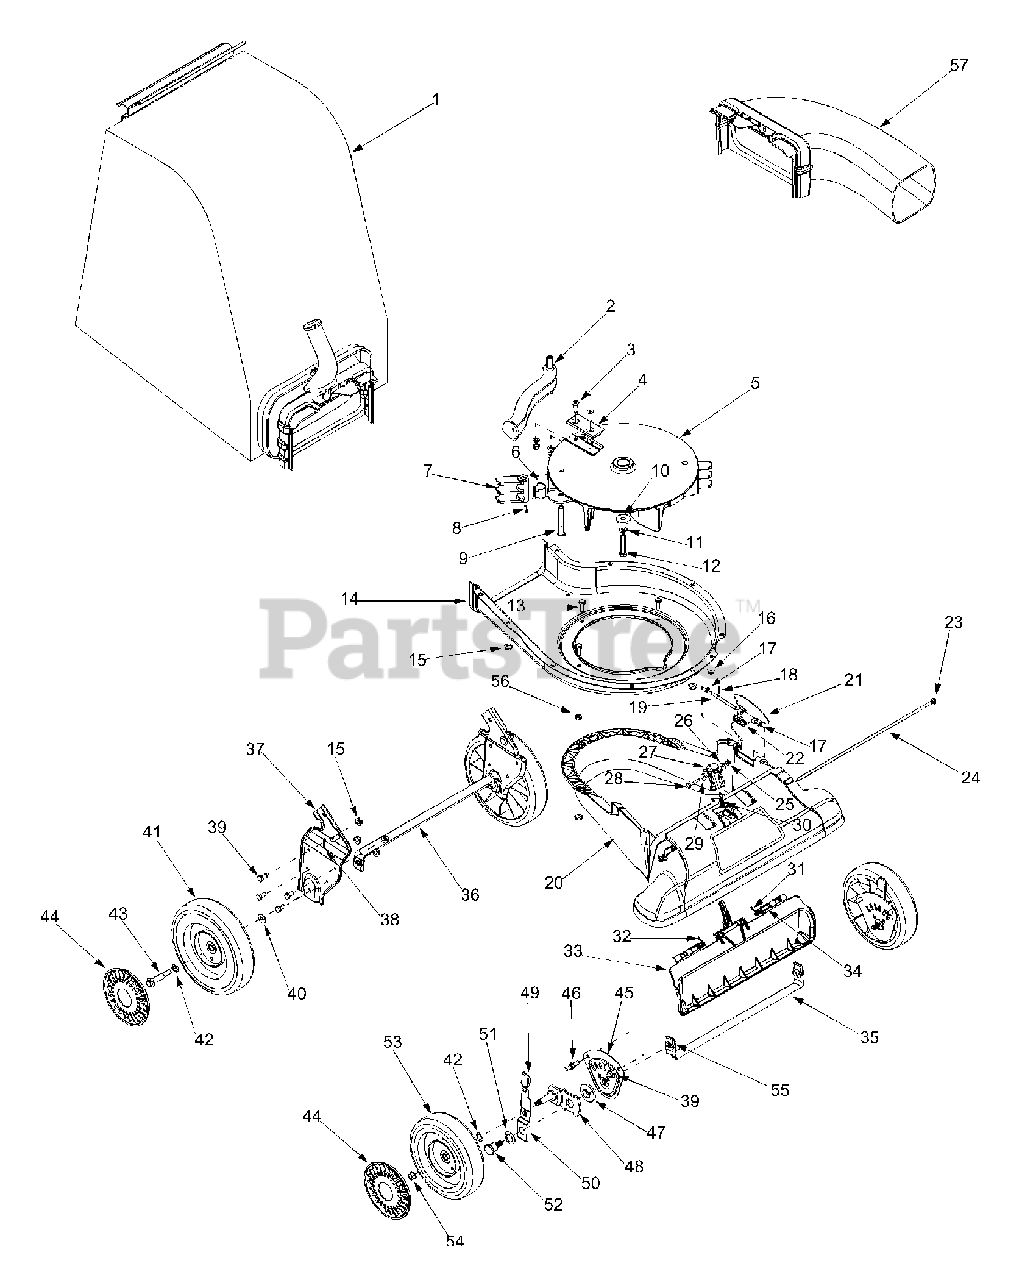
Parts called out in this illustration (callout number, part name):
1	Bag Only
2	Screen Assembly
3	Hex Screw 5/16-24 x 1.0
4	Chipper Blade
5	Impeller Assembly
6	Pin Clip
7	Flail Blade
8	Spiral Pin
9	Clevis Pin
10	Flat Washer.375 ID x 1.25 OD
11	Lock Washer 3/8
12	Hex Cap Screw 3/8-24 x 2.0
13	Hex Cap Screw 5/16-18 x .875
15	Flange Lock Nut 5/16-18
16	Hex Flange Nut 1/4-20
17	Flat Washer .281 ID x .50 OD
18	Cotter Pin
19	Pivot Rod
20	Nozzle
21	Base Adapter Door
22	Torsion Spring
23	Cap Speed Nut 1/4
24	Pivot Rod
25	Hex Lock Nut #10-24
26	Flat Washer .194 ID x .62 OD
27	Nozzle Door Lever
28	Hex Screw #10-24 x 1.25
29	Shoulder Spacer
30	Extension Spring
31	Torsion Spring LH
32	Torsion Spring RH
33	Nozzle Door
34	Rod .25 x 1.25 Lg
35	Front Wheel Support Brace
38	Cotter Pin
39	Hex Cap Screw 5/16-18 x.625
40	Bell Washer.401 ID x.870 OD
41	Wheel 9 x 2
42	Wave Washer .531 ID x .781 OD
43	Shoulder Screw 3/8-16
44	Hubcap
45	Height Adjustment Bracket
46	Stud 5/16-18 .56 x .75
47	Height Adjustment Bearing
48	Pivot Arm Assembly
49	Height Adjustment Knob
50	Spring Lever
51	Bell Washer .760 ID x .25 OD
52	Shoulder Screw .750 ID x .625 OD
53	Wheel 8 x 2
54	Flange Lock Nut 3/8-16
55	Lock Nut 3/8-16
56	Hex Lock Nut 5/16-18
57	Blower Chute
